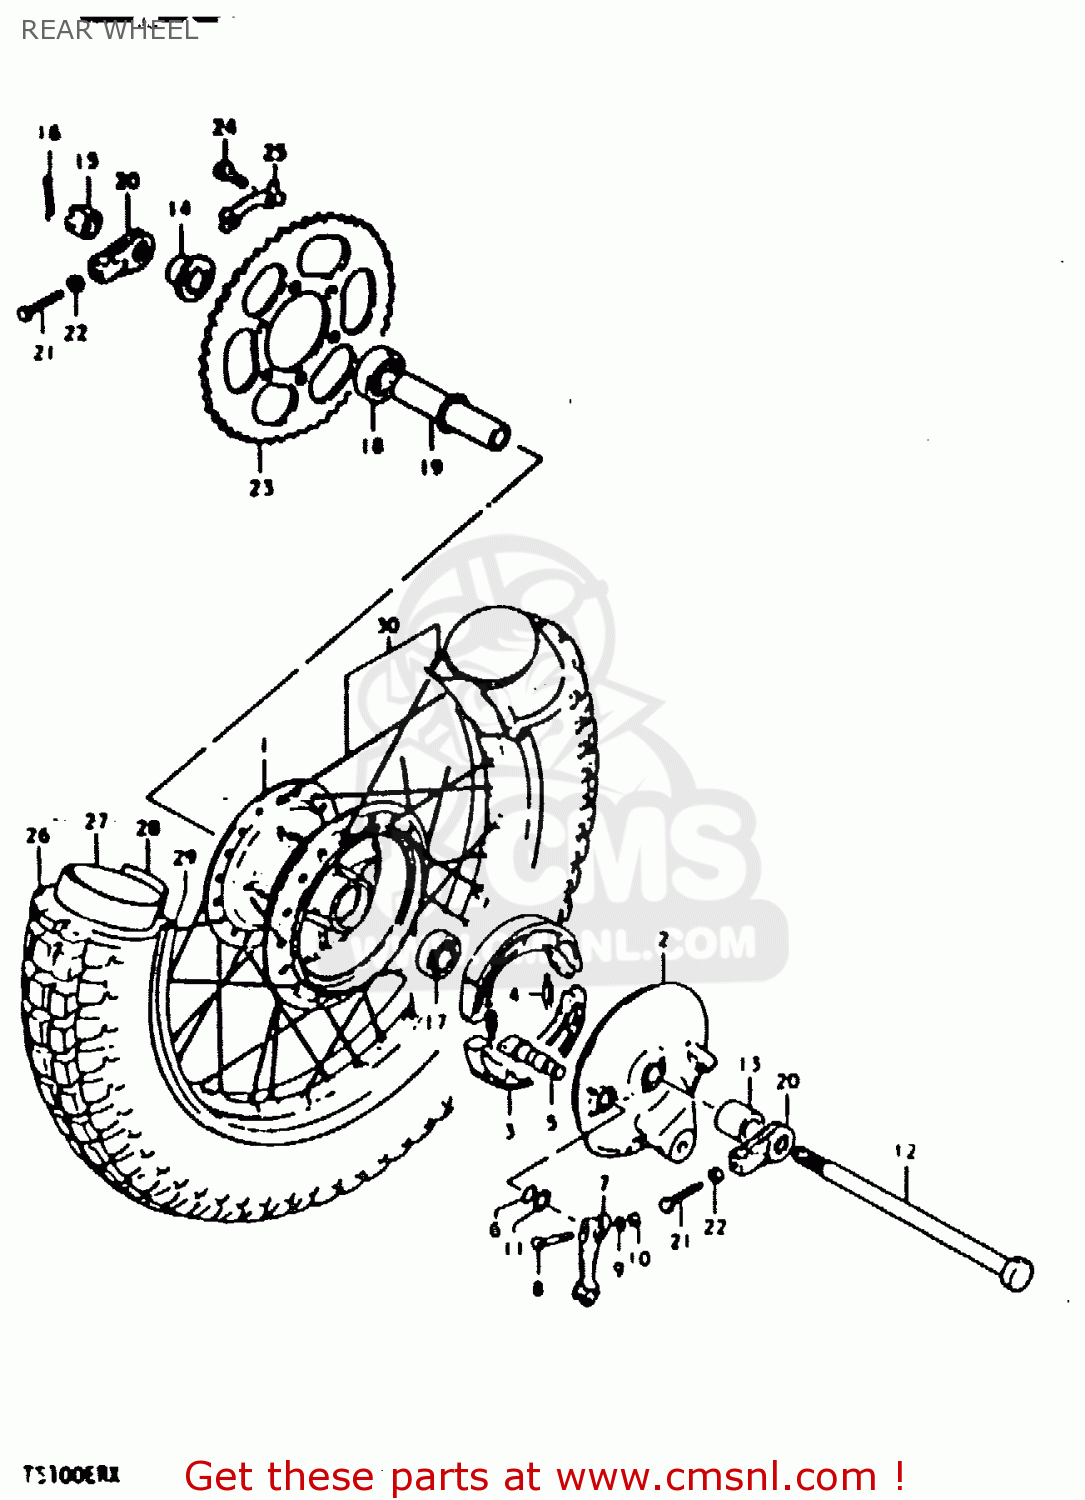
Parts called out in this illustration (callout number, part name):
1	HUB,REAR WHEEL
2	PANEL,RR BRAKE ANCHOR
3	SHOE,BRAKE
4	SPRING(L:34)
5	CAM,FRONT BRAKE
6	O-RING (D:2.4 ID:13.8)
7	LEVER,RR BRAKE CAM
8	BOLT 6X40
9	WASHER
10	NUT
11	WASHER (14.5X22X1.6)
12	AXLE,REAR
13	SPACER(15.2X22X26)
14	SPACER,RR AXLE,L
15	NUT
16	COTTER PIN
17	BEARING
18	BEARING
19	SPACER,RR WHEEL HUB BEARING
20	ADJUSTER,CHAIN
21	BOLT(8X40)
22	NUT
23	SPROCKET,REAR
24	BOLT(8X30)
25	WASHER
26	TIRE 3.00-18 077-458MM
27	TUBE,INNER
28	PROTECTOR,INNER TUBE
29	RIM,RR WHEEL
30	SPOKE SET
